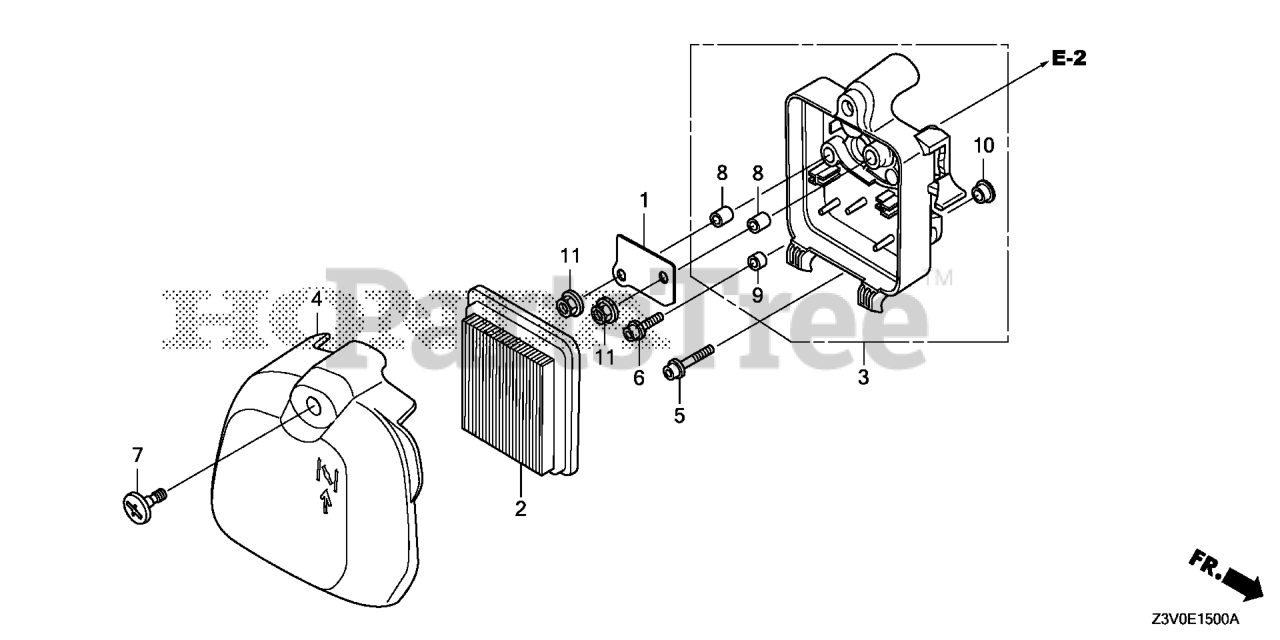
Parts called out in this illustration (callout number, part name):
1	PLATE, OIL TRAP
2	ELEMENT, AIR CLEANER
3	HOUSING, AIR CLEANER
4	COVER, AIR CLEANER
5	BOLT, SOCKET (5X25)
6	BOLT, SOCKET (5X16)
7	SCREW, SPECIAL (6X16)
8	COLLAR, AIR CLEANER HOUSING (A)
9	COLLAR, AIR CLEANER HOUSING (B)
10	COLLAR, AIR CLEANER HOUSING (C)
11	NUT, FLANGE (5MM)
